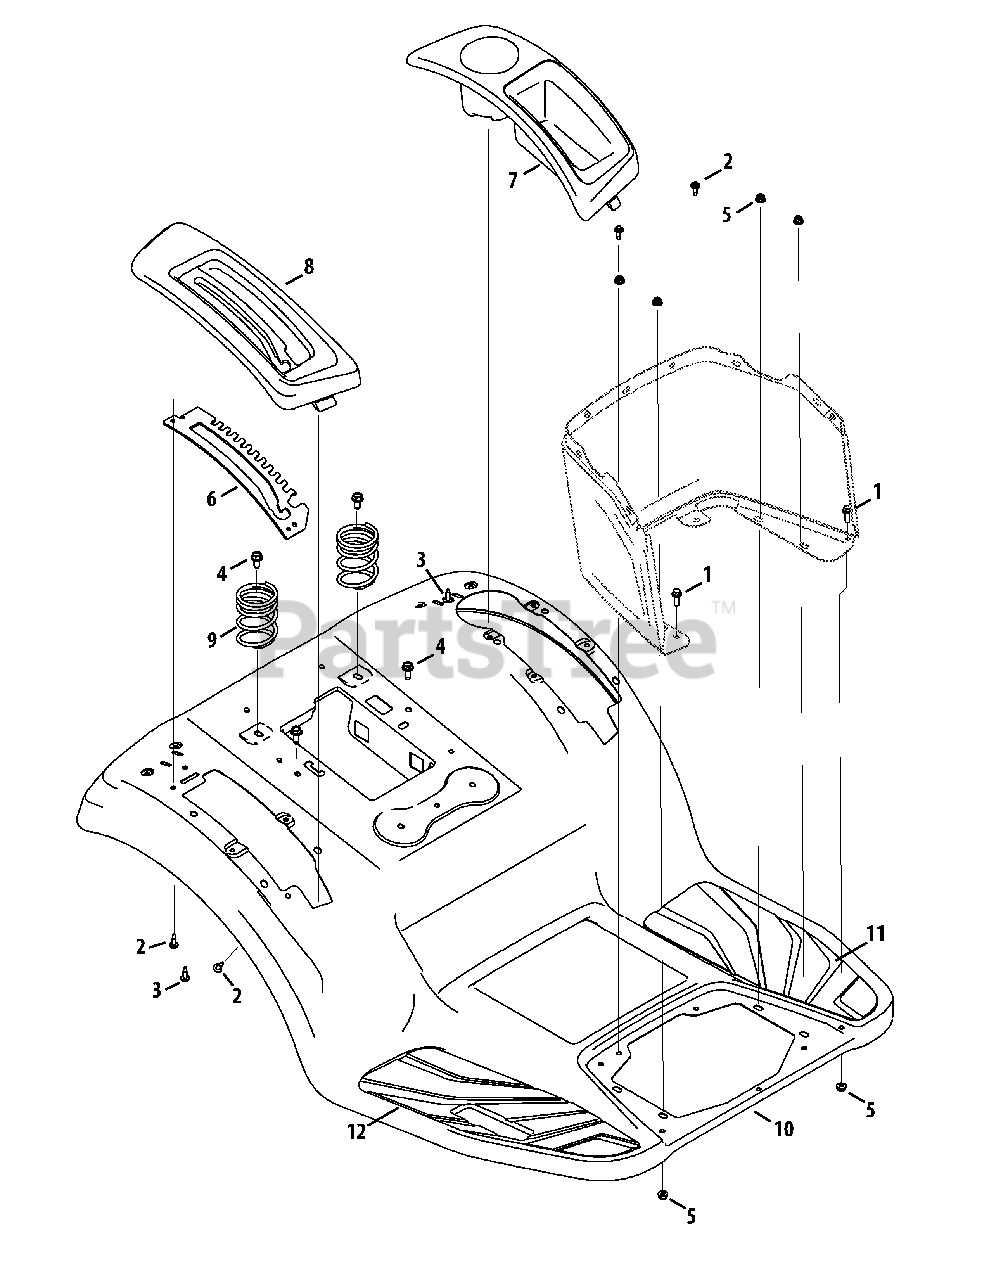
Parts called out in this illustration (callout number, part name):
1	Hex flange Screw, 1/4-20 x .75
2	Screw, M6-1 x .625
3	Screw, 1/4-10 x .75
4	Screw, Self-tapping, 5/16-18, 0.750,
5	Nut, Flange Lock, 1/4-20, Nylon
7	Cover, LH
8	Cover, RH, Electric PTO
9	Compression Spring, 2.50 x 3.951 x .207
10	Fender
11	Pad, Foot, LH
12	Pad, Foot, RH
